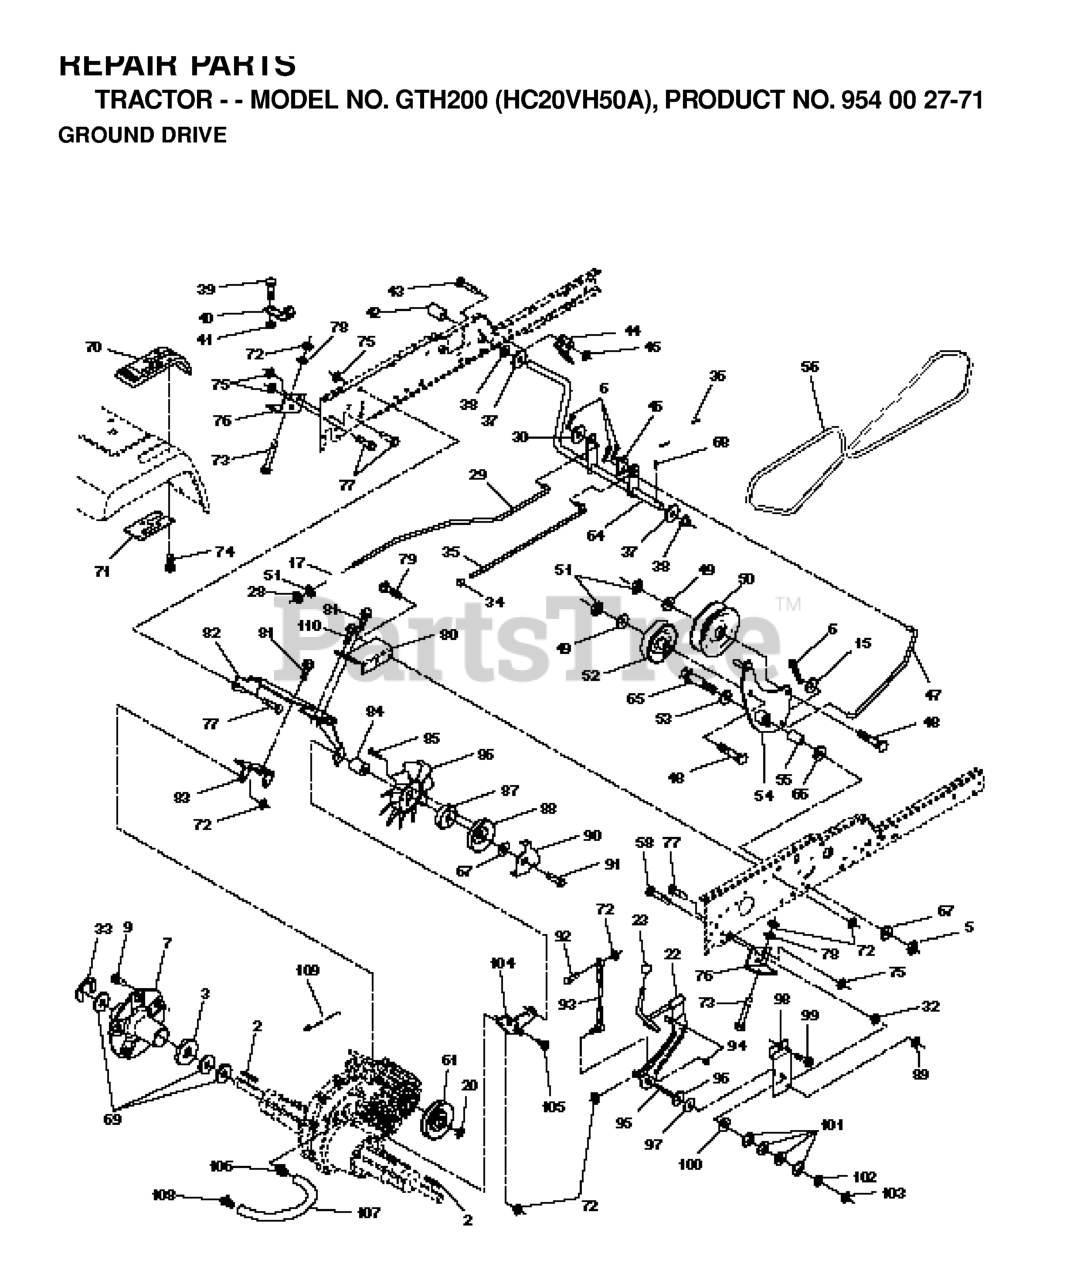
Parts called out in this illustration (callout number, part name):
2	KEY 1/4 X 2.5
6	COTTER PIN
7	HUB ASMBLY
15	WASHER
17	SPRING.ROD.BRAKE
20	NUT.HEX.1/2-20
22	SHAFT ARM ASMBLY
23	KNOB.DELUXE.(PISTOL.GRIP).BLAC
28	NUT
30	WASHER
33	E RING HYT
34	CAP
35	PARKING BRAKE ROD
36	SPRING EXTENSION
39	Screw, Fin. #10-24 x 1
40	ACT-SWITCH T
41	LOCKNUT
42	COVER, PEDAL (1 2)
43	BOLT.HEX.1/4.X.3/4.DICHROMATE
44	BRKT SWITCH GT
45	LOCKNUT.NYLOC.1/4-20
46	RETAINER SPRING
47	CLUTCH ROD
49	Washer 13/32 x 7/8 x 13 Gauge
50	FLAT IDLER PULLEY
51	NUT
52	PULLEY.IDLER.V.
54	CLUTCH ARM ASSY
55	BEARING LT (2 2)
58	BOLT.HEX.7/16-14.FINISHED
64	PEDAL SHAFT
66	WASHER.BLADE
67	WASHER
68	ROLL PIN STD
70	CONSOLE
71	PLATE SHIFT CONSOLE
72	NUT.71038.31-18.HEX.NYLOCK
73	Bolt Fin Hex 5/16-18 x 3
74	SCREW.HI-LO.CONSOLE
75	Nut, Lock Hex 7/16 Unc
76	BRACKET TRANSAXLE
77	BOLT
79	BOLT.CARR.5/16-18X5/8.SHORT
80	TORQUE BRACKET RH
81	SCREW
82	BRACKET
83	STRAP TORQUE MID
85	Screw #10-24 x 1-1/4
86	FAN 7" HYDRO
87	ADAPTOR.FAN.TRANSAXLE.VGTH
88	IDLER PULLEY
89	Nut, Crownlock Hex 7/16-14 unc
90	KEEPER.BELT
91	SCREW.HXWSH.3/8
92	BOLT
93	LINK ASM SHIFT
94	FASTENER.XMAS.TREE
95	Screw Set 5/16-18 x 1.75
98	SHIFT BRACKET
99	SCREW LT
102	NUT
103	JAM NUT TI
104	BRACKET IDLER
105	SCREW CRT
106	VENT FITTING
108	VENT CAP 70109
109	RETURN SPRING
110	HINGE SCREW
